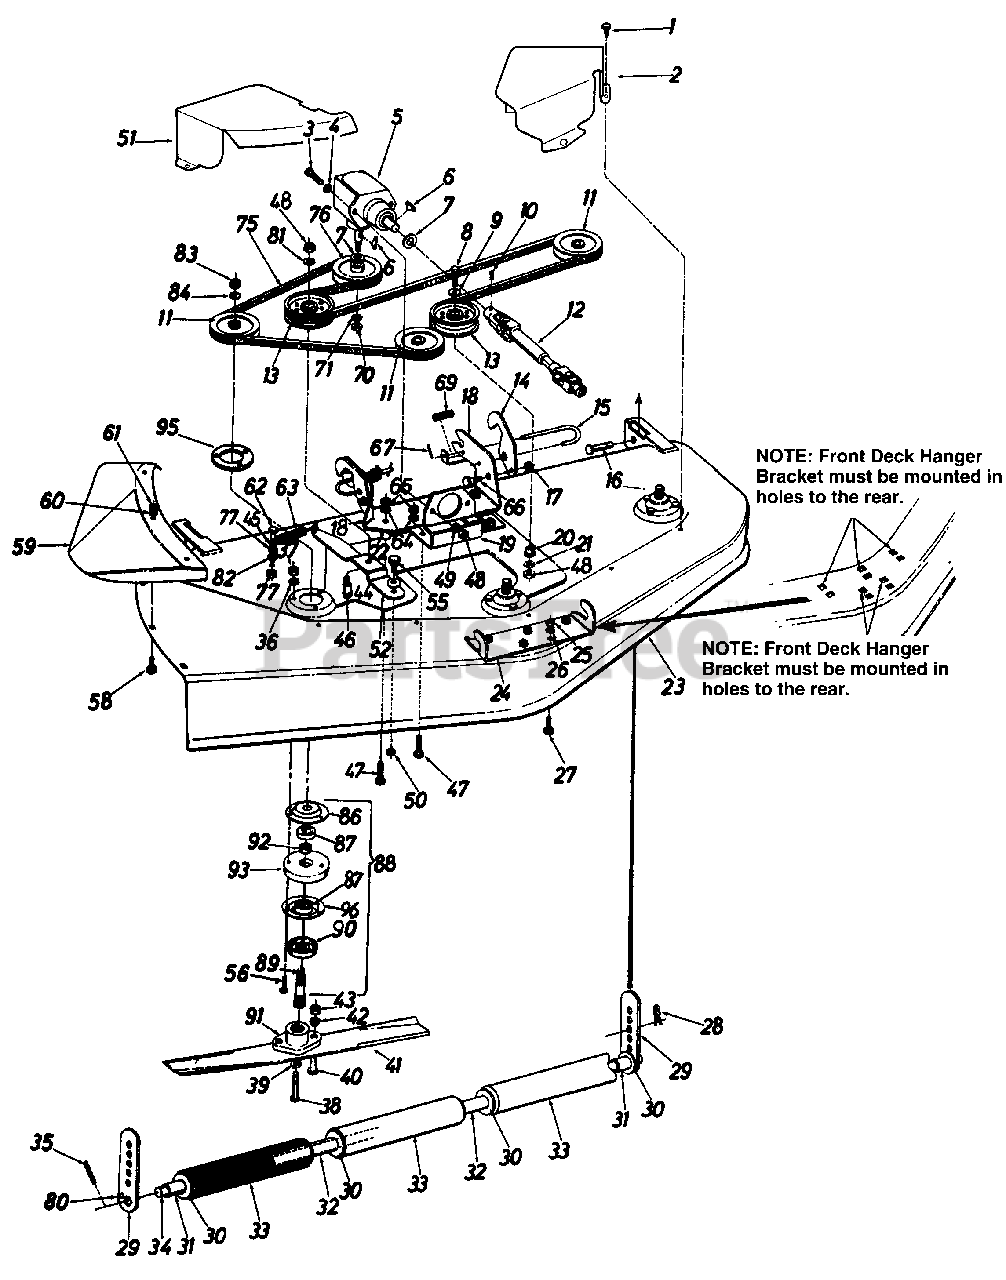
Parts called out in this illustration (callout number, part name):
1	Hex TT-Tap Scr. 1/4-20 x .5" Lg.
3	Hex Bolt 3/8-16 x 1.25" Lg.
4	Ext. L-Wash. 3/8" I.D.
5	Right Angle Drive
6	#9 Hi-Pro Key 3/16 x 3/4" Dia.
7	Fl-Wash. 29/32" I.D.
8	Hex Bolt 3/8-16 x 2.25" Lg.
9	Fl-Wash. 3/8" I.D.
10	Sq. Hd. Set Scr. 3/8-16 x .50"
11	Deck Pulley
12	Universal Drive Shaft Ass'y.
12	Universal Drive Male Half
12	Universal Drive Female Half
13	Deck Idler Pulley
14	Hanger Lock
15	Release Pin
16	Clevis Pin .50" Dia.
17	Hex L-Nut 5/16-18 Thd.
21	L-Wash. 3/8" I.D.
22	Spacer .33" I.D. x .88" O.D.
26	L-Wash. 5/16" I.D.
27	Carriage Bolt 5/16-18 x .75" Lg.
28	Internal Cotter Pin
30	Fl-Wash. .75" I.D. x 1.5" O.D.
31	Spacer .758" I.D. x 1.25" O.D. x .530
34	Roller Shaft
35	Roll Pin 3/16 x 1.25"
36	L-Wash. 5/16" I.D.
37	Hex Cent. L-Nut 5/16-24 Thd.
38	Hex Self-Tap Scr. 3/8-24 x .75" Lg. (Gr. 5)
38	Hex Bolt 3/8-24 x .88" Lg. (Gr. 5)
39	L-Wash. 3/8" I.D. H.D.
40	Hex Bolt 5/16-24 x 1" Lg.
41	Blade 17" (Round hole blade)
42	L-Wash. 5/16" I.D.
43	Hex L-Nut 5/16-24 Thd.
44	Spr. Wash..445" I.D.
45	Fl-Wash. 1/4" I.D.
46	Shld. Scr. .625" Dia. x .96"
47	Carriage Bolt 5/16-18 x 1.5" Lg.
48	Hex Nut 3/8-16 Thd.
49	L-Wash. 3/8" I.D.
50	Hex L-Nut 7/16-14 Thd.
56	Hex Bolt 5/16-24 x 1.5" Lg. (Grade 5)
56	Screw-Rib Neck 5/16-24 x 1.12" Lg.
58	Carriage Bolt 5/16-18 x .75" Lg.
60	L-Wash. 5/16" I.D.
61	Hex Nut 5/16-18 Thd.
62	Hex Bolt 1/4-28 x 1-3/4" Lg.
63	Extension Spring
64	L-Wash. 5/16" I.D.
65	Hex Nut 5/16-18 Thd.
66	Shld. Bolt
67	Roll Pin 1/8" Dia.
69	Compression Spring
70	Hex L-Nut 5/8-18 Thd.
71	L-Wash. 5/8" I.D.
75	V-Belt 1/2"
76	Drive Pulley
77	Hex L-Nut 1/4-28 Thd.
80	Spring Pin Spiral 1/4" Dia. 1.00" Lg.
81	Bell-Wash. 3/8" I.D. x . 87" O.D.
82	L-Wash. 1/4" I.D."
83	Hex Jam Nut 5/8-18 Thd.
84	L-Wash. 5/8" I.D.
86	Bearing Housing
87	Ball Bearing
88	Deck Spindle Assembly 3/4"
88	Deck Spindle Assembly 1"
89	Spindle 3/4"
90	Bearing Shield
91	Blade Adapter 3/4"
91	Blade Adapter 1"
92	Spacer
95	Spindle Reinforcement Plate
96	Open Bearing Housing
96	Bearing Housing w/bearing 741-0919A
